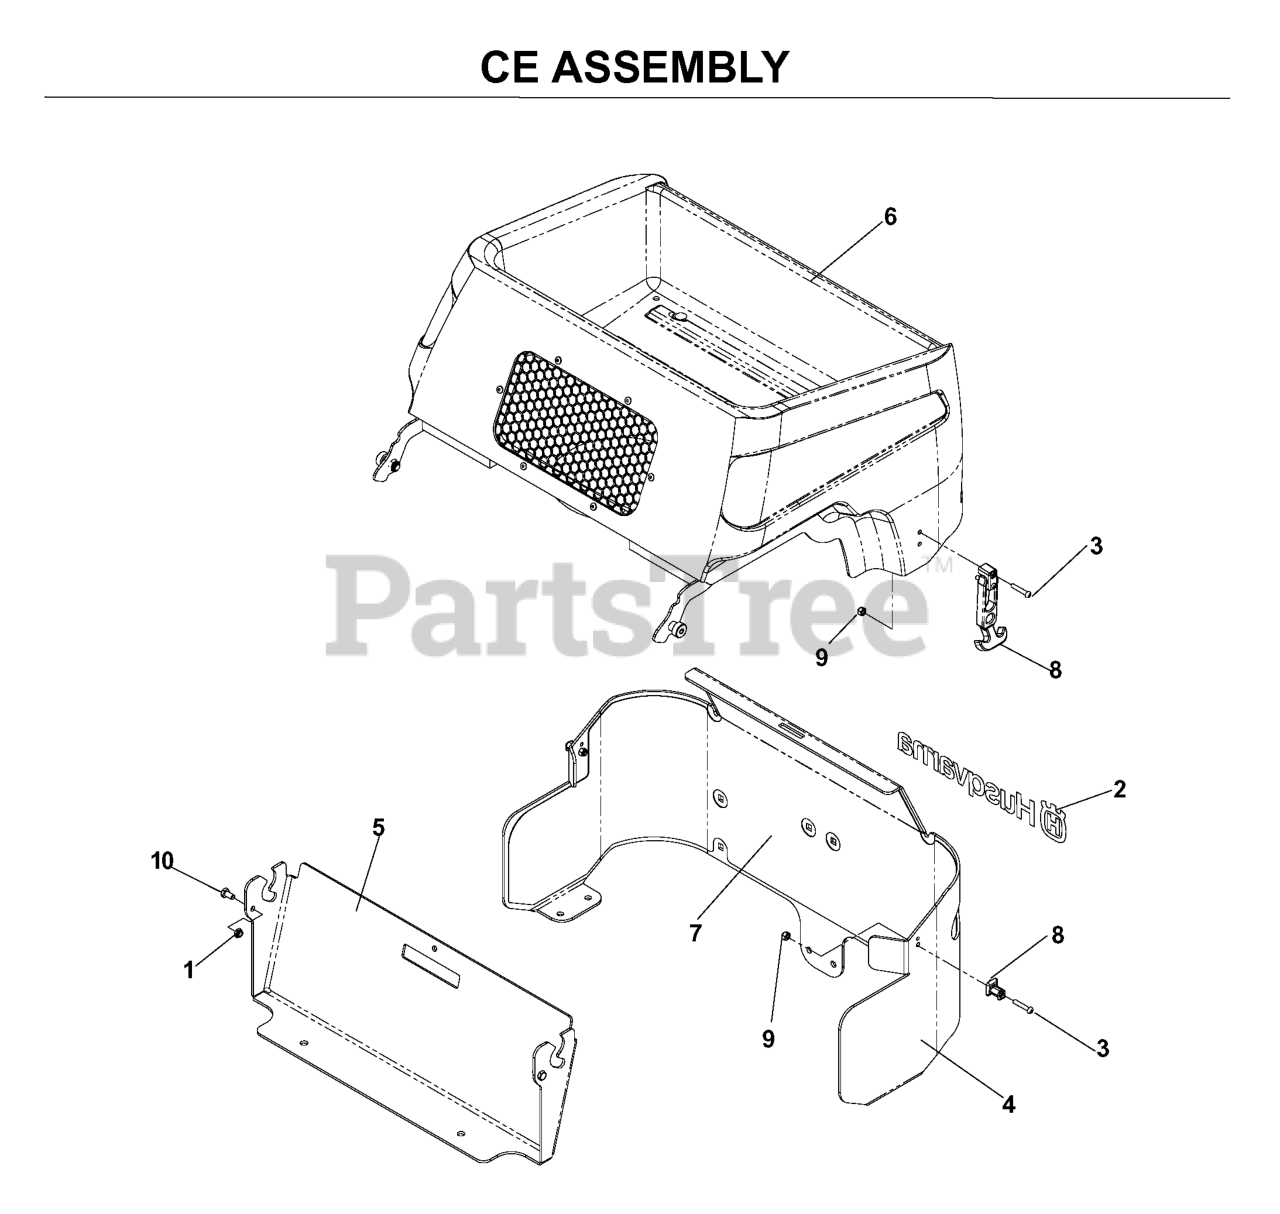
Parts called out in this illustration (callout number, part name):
1	JAM NUT 1/4C (2 2 PW01)
2	DECAL, HUSQ 12" BLUE
3	SCR, #10-24 X 1-1/8
4	REAR GUARD
5	FRONT SUPPORT
6	HOOD ASSEMBLY, Z
7	BARRIER, HEAT
8	DRAW LATCH, FLEXIBLE T-HANDLE
9	NUT 10-24 NYLOC
10	HCS 1/4-20.
